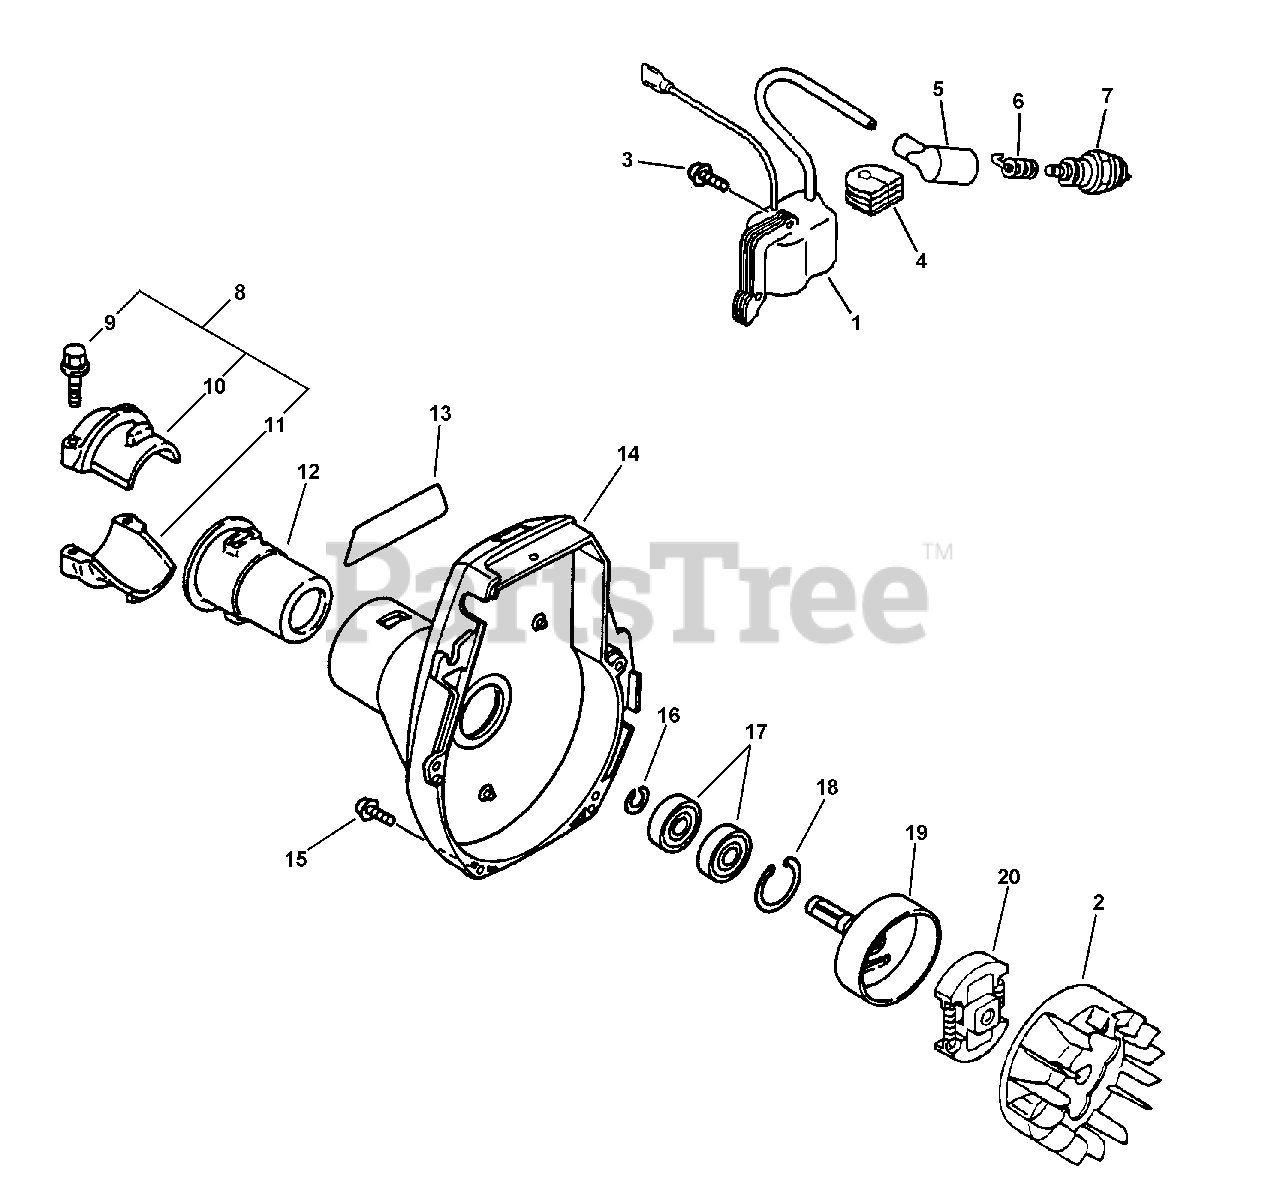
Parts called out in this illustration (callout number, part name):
1	COIL, IGNITION
2	FLYWHEEL
3	SCREW 4×22
5	CAP, SPARK PLUG
6	TERMINAL, SPARK PLUG
7	SPARK PLUG - BPM7A
8	RETAINER KIT
9	BOLT - 5×25
10	HOLDER, MAIN PIPE - UPPER
11	HOLDER, MAIN PIPE - LOWER
12	CUSHION Ø25
13	LABEL - MODEL SRM-2100
13	LABEL - MODEL SRM-2110
14	COVER ASSY, FAN
15	BOLT 4×16
16	RING, RETAINING - 12
17	BEARING, BALL 6001
18	RING, SNAP 28
19	DRUM, CLUTCH
20	CLUTCH ASSY
